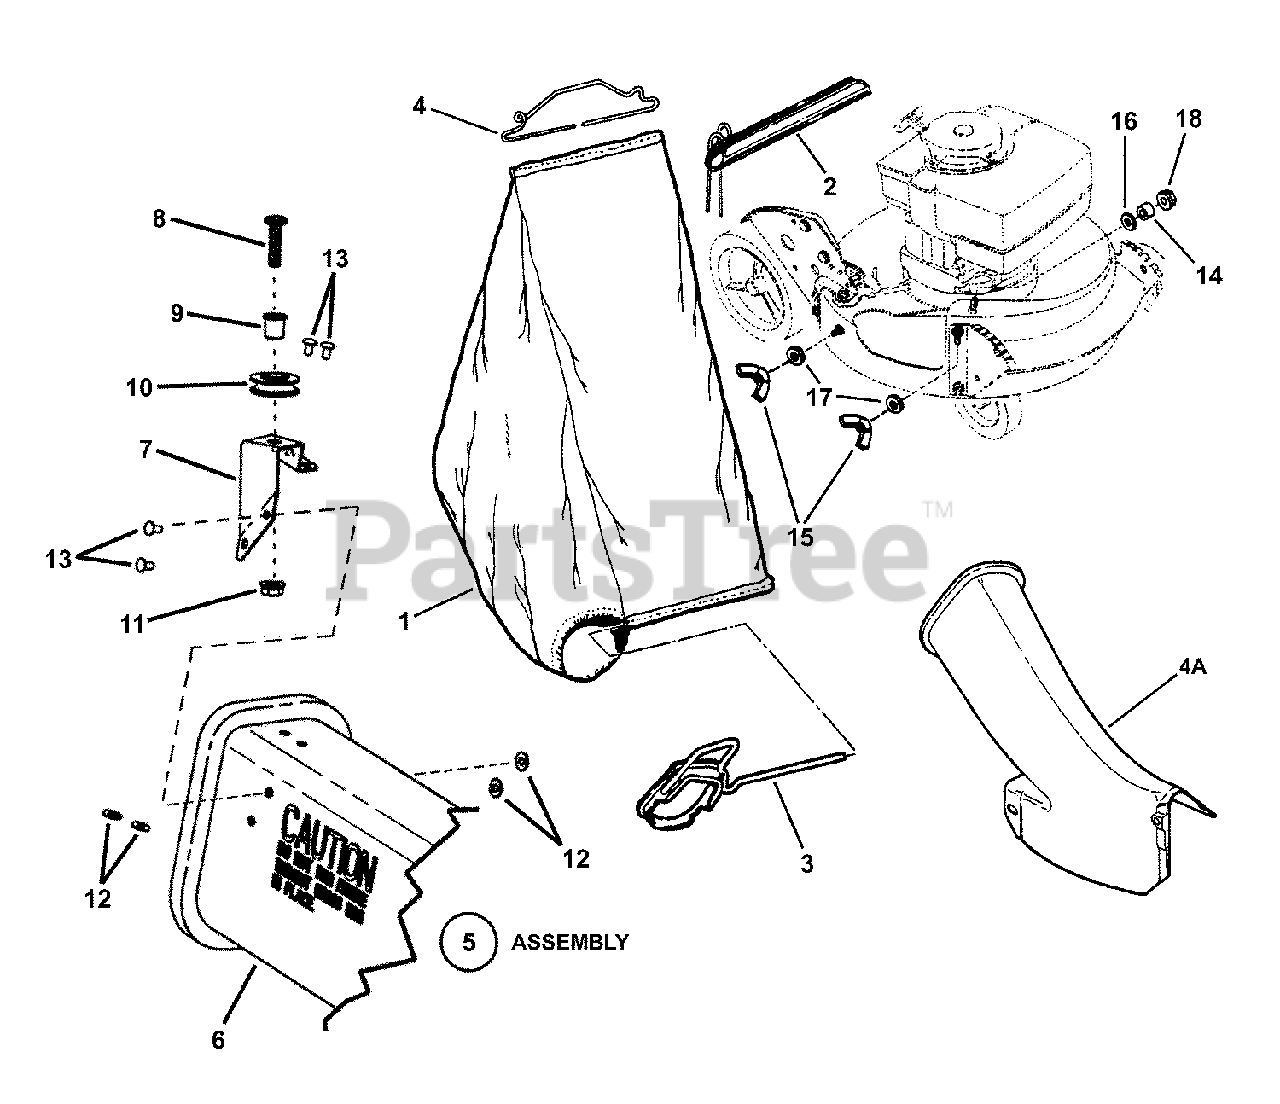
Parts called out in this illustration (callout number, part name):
1	BAG, Grass Slider (Black/Gold) (10.75" Wide)
2	ASSEMBLY, Slider
3	CONNECTOR, Grass Bag (weldment)
4	WIRE, Bag Connector (12" Wide)
4A	ADAPTER, Grass Bag
5	ASSEMBLY, Grass Bag Adapter (Includes items 6 thru 13)
6	ADAPTER, Bag
7	BRACKET, Rope Pulley
8	SCREW, 5/16-18 x 1-1/4" Pan Head Machine
9	BUSHING, Flange
10	PULLEY, Plastic
11	NUT, 5/16-18 Hex Flange Lock GR5
12	WASHER, 15/32" Flat
13	RIVET, 3/16 x .344
14	SPACER
15	NUT, 5/16-18 Wing (Nylon Patch)
16	RETAINER, 5/16" Bolt
17	WASHER, 5/16" Flat
18	NUT, 5/16-18 Hex Large Flange Center Lock
